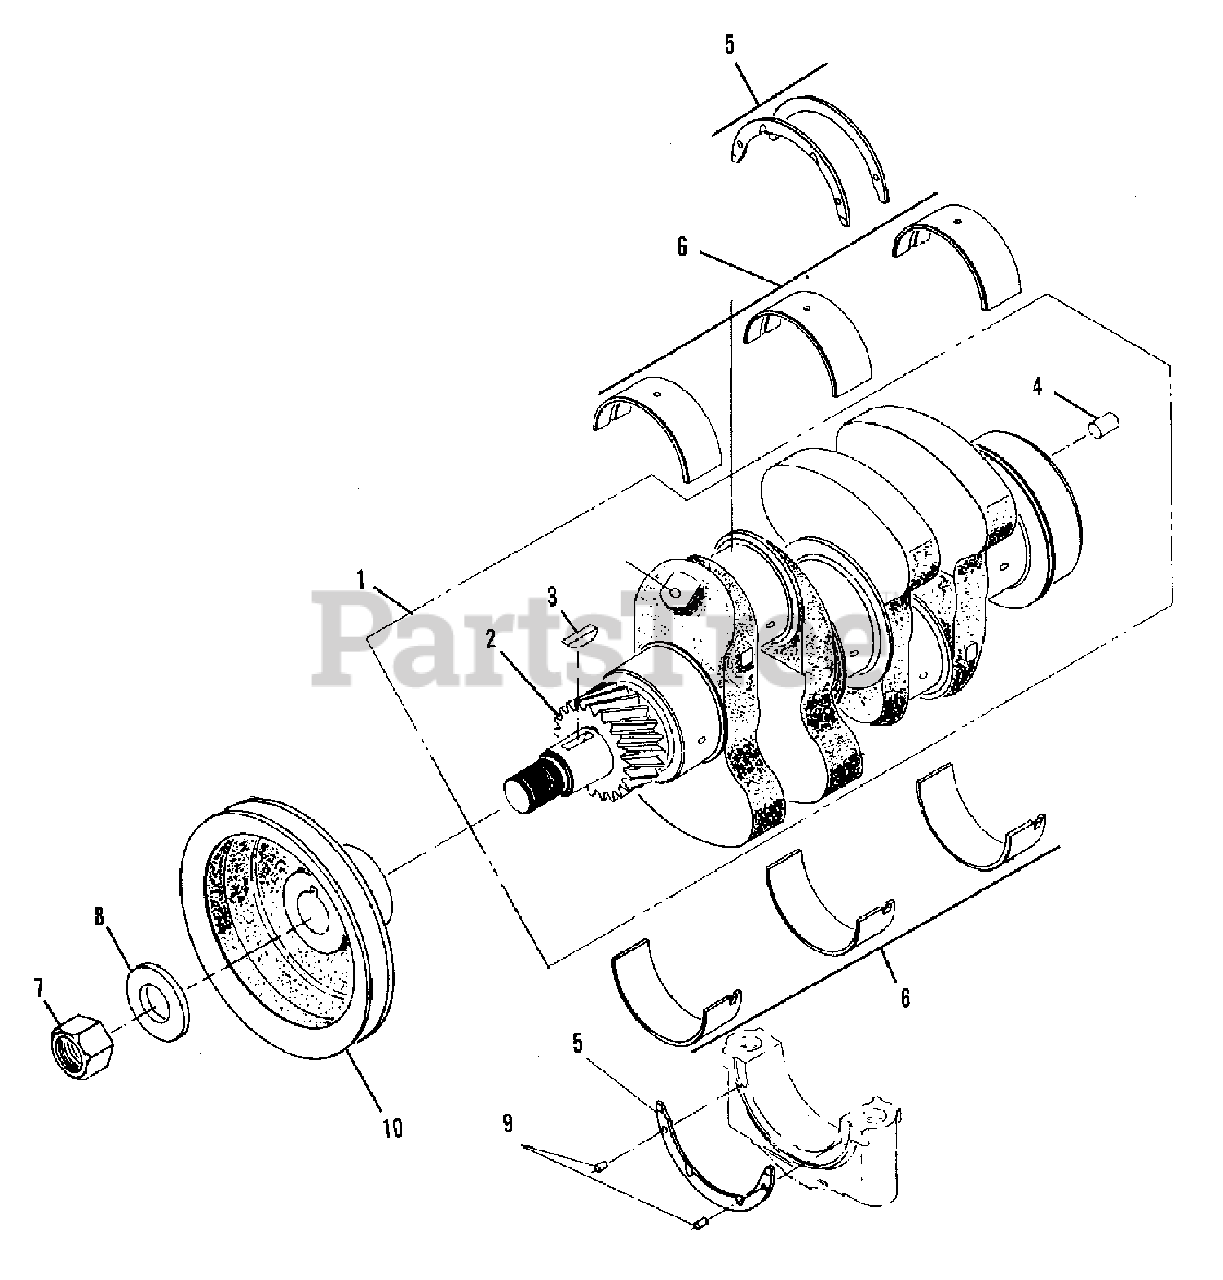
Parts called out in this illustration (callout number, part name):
1	CRANKSHAFT ASSEMBLY (Incl. Items 2 thru 4)
2	GEAR, crankshaft
4	PIN, dowel
5	FLANGE KIT, thrust (Std.)
5	FLANGE KIT, thrust (O.S. 0.25)
6	BEARING KIT, main (Std.) (Incl. 3 UPPER & 3 LOWER MAIN BEARINGS)
6	BEARING KIT, main (U.S. 0.25) (Incl. 3 UPPER & 3 LOWER MAIN BEARINGS)
6	BEARING KIT, main (U.S. 0.50) (Incl. 3 UPPER & 3 LOWER MAIN BEARINGS)
8	WASHER, pulley
9	PIN, thrust flange groove
10	PULLEY, crankshaft
